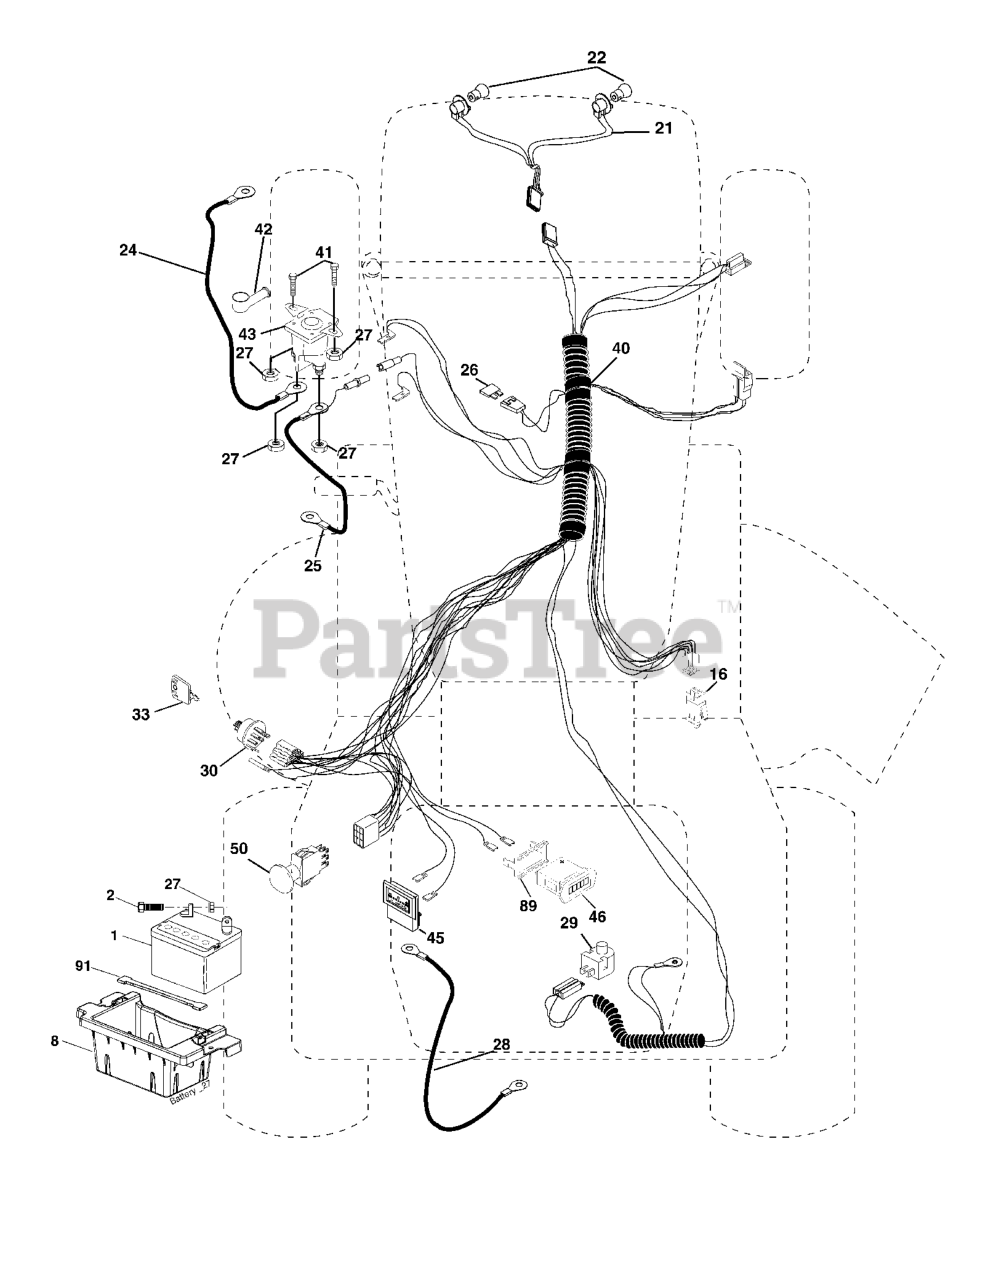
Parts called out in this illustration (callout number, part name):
1	BATTERY 12V .35 AMP
2	BOLT.HEX.1/4.X.3/4.DICHROMATE
8	BOX.BATTERY.MOUNT.FRONT.LT
16	SWITCH INTERLOOK PUSH-IN
21	HARNESS ASSY LIGHT
22	LIGHTBULB
24	BATTERY CABLE GT
25	CABLE BATTERY 6 GA 22" W/16W
26	FUSE 20AMP
27	NUT
28	CABLE GROUND 6 GA 21" 90T BLK
29	RP.SWITCH.PLUNGER.NC.GRAY
30	IGNITION SWITCH
33	KEY MLD GEN DELTA
40	HARNESS.IGNITION
41	BOLT
42	TERMINAL COVER
43	SOLENOID
45	AMMETER
46	HOUR METER
50	RP.PTO.SWITCH.8 TERMINAL.BLACK
89	BRACKET SNAP-IN HOURMETER
90	COVER TERMINAL
91	STRAP.BATTERY.MOUNT.FRONT(2 2)
